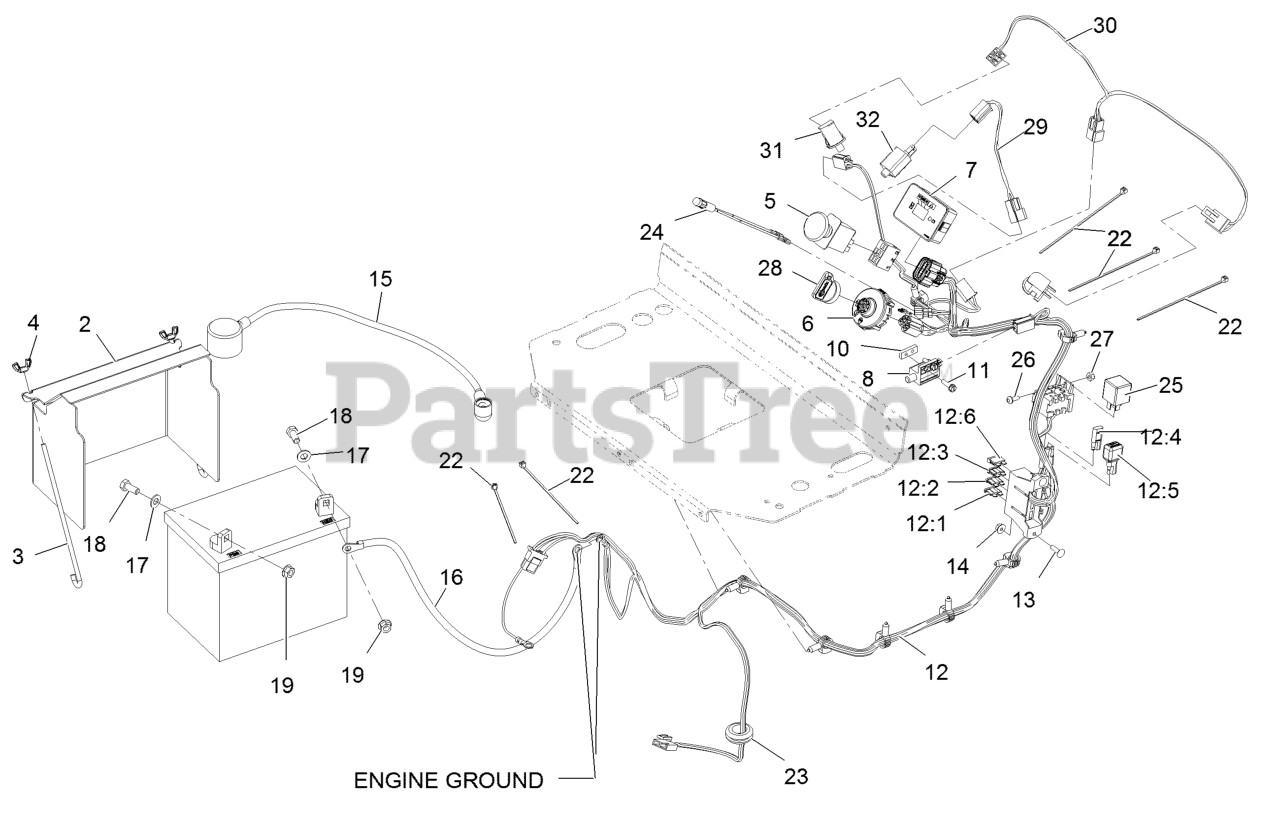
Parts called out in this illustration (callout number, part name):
2	COVER-BATTERY
3	BOLT-HOLDDOWN
4	WINGNUT
5	SWITCH-PTO, ON-ON
7	MODULE-HOUR METER
8	SWITCH-CLOSED, NORMALLY
10	PLATE-TAPPED
11	SCREW-HWH
12	HARNESS-WIRE, EFI
12:1	FUSE-BLADE, 30 AMP
12:2	FUSE-BLADE, 25 AMP
12:3	FUSE-BLADE, 10 AMP
12:6	FUSE-BLADE, 15 AMP
13	SCREW-CARR
15	CABLE-BATTERY, POSITIVE
16	CABLE-BATTERY, BLACK
17	WASHER-PLAIN
18	SCREW-HH
19	NUT-HHF, SMOOTH
22	TIE-CABLE
23	GROMMET
24	INDICATOR-LED, RED
26	SCREW-PPH
27	NUT-LOCK, NI
28	KEY-IGNITION
29	HARNESS-NEUTRAL
30	HARNESS-OPC
31	SWITCH-BAIL
32	SWITCH-OPEN, NORMALLY
